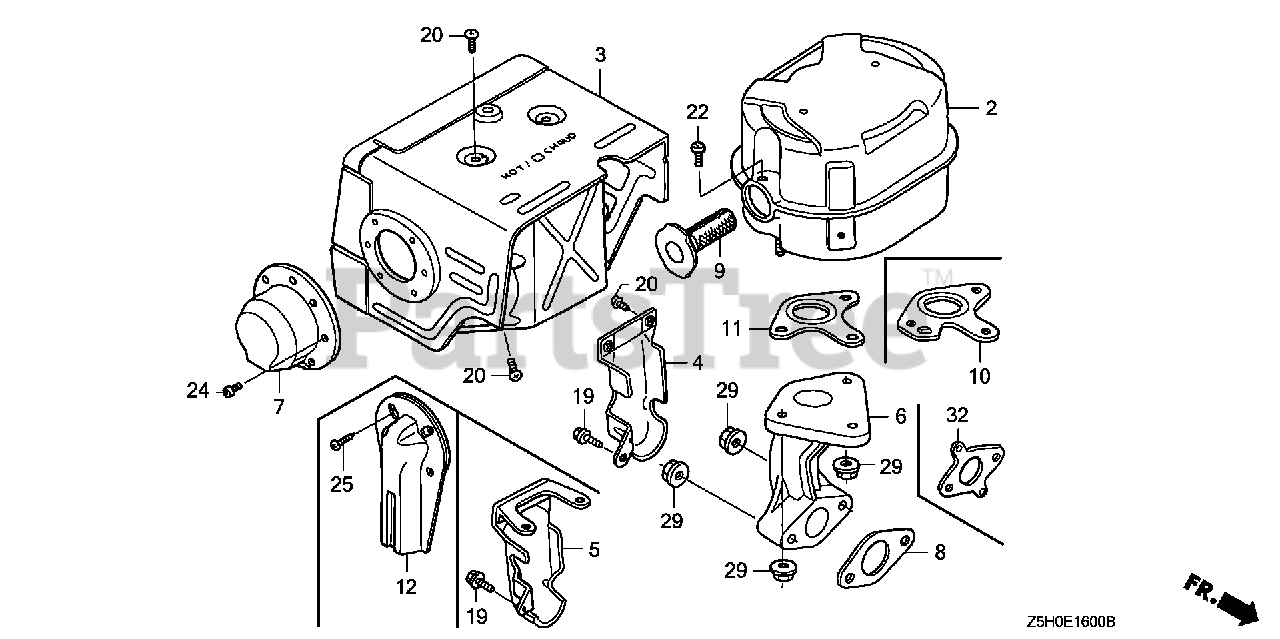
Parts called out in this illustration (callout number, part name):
2	MUFFLER
3	PROTECTOR, MUFFLER (STD)
4	PROTECTOR, EX. PIPE
7	CAP, MUFFLER
8	GASKET, EX. PIPE
9	ARRESTER, SPARK
10	GASKET, MUFFLER (ARRESTER) (NIPPON LEAKLESS)
11	GASKET, MUFFLER (NIPPON LEAKLESS)
19	BOLT, FLANGE (6X12) (CT200)
20	SCREW, TAPPING (5X8)
22	SCREW, TAPPING (4X6)
24	SCREW, TAPPING (4X6)
29	NUT, FLANGE (8MM)
